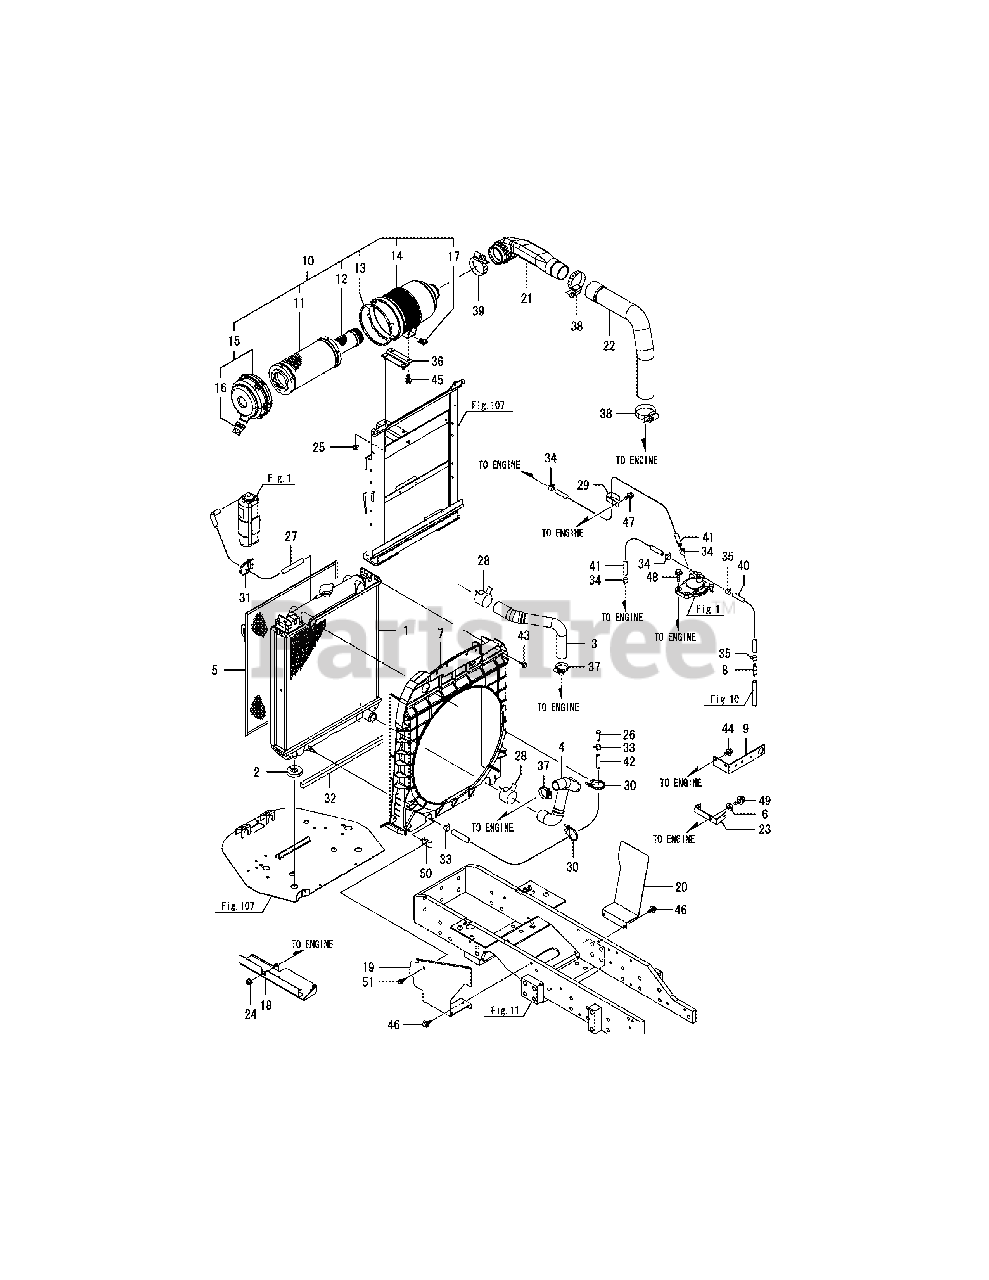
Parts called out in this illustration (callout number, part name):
2	RUBBER,RADIATOR
3	TUBE,COOLING WATER A
4	PIPE, COOLING WATER
5	SCREEN, RADIATOR
7	SHROUD M ASSY, FAN
9	CLAMP, FUEL HOSE
10	CLEANER ASSY,5.5IN,D
11	ELEMENT ASSY, OUTER
12	ELEMENT ASSY, INNER
13	GASKET, AIR CLEANER
16	VALVE, UNLOADER
18	PLATE,SHUTTER,88 ASS
21	PIPE A, INTAKE
22	HOSE B, INTAKE
23	BRACKET, CLAMP
24	NUT W/WASHER 8
25	NUT W/WASHER 8
27	PIPE, C. WATER
29	CLAMP, WIRE HARNESS
32	URETHANE,SIDE LAMP
36	SUPPORT, CLEANER
40	HOSE 7.3X200,BRAIDED
41	FUEL PIPE 7.3X400
42	FUEL PIPE 7.3X600
43	BOLT M 6X 20 PLATED
44	BOLT M 8X 12 PLATED
45	BOLT M 8X 16 PLATED
46	BOLT M 8X 16 PLATED
47	BOLT M 8X 16 PLATED
48	BOLT M 8X 30 PLATED
49	BOLT M10X 20 PLATED
51	BOLT M 6X 20 PLATED
